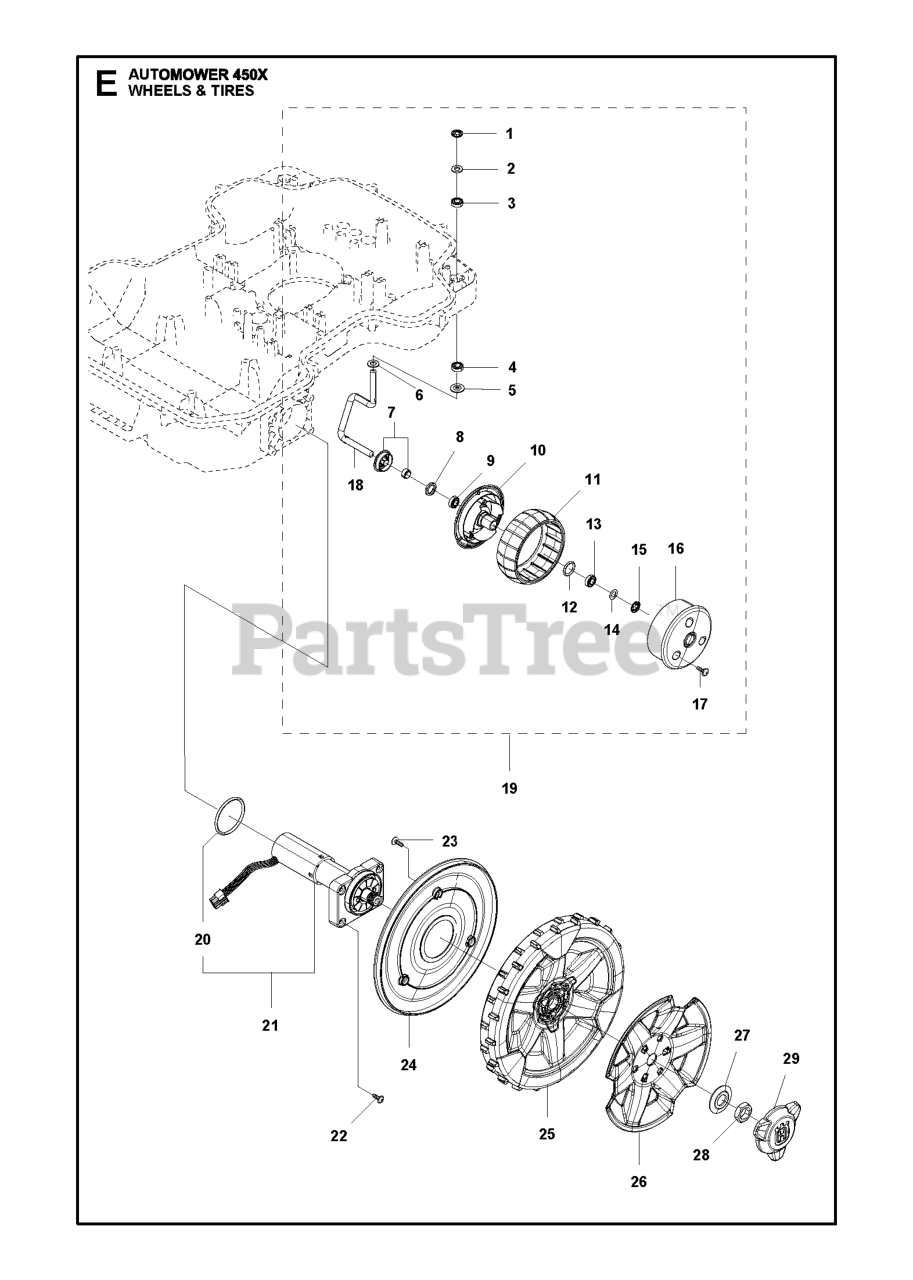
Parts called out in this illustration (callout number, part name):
1	LOCKWASHER PUSH-ON TYPE P 8 BV
2	WASHER DIN 988 13X8X0.5
3	BALL BEARING SINGLE ROW S688
4	BALL BEARING SINGLE ROW S688
5	WASHER FRONT WHEEL CENTER HOLE
6	WASHER DIN 988 13X8X0.5
7	SHIELD KIT
8	SEALING 12X18X3
9	BALL BEARING SINGLE ROW S688
10	WHEEL FRONT WHEEL INSIDE
11	WHEEL RUBBER TYRE
12	O-RING 2,62X15,54
13	BALL BEARING SINGLE ROW S688
14	WASHER DIN 988 13X8X0.5
15	LOCKWASHER PUSH-ON TYPE P 8 BV
16	WHEEL FRONT WHEEL OUTSIDE
17	SCREW 14MM
18	SPINDLE SPINDLE FRONT WHEEL RI
19	WHEEL KIT FRONT
20	O-RING LIGHT GREY
21	MOTOR KIT DRIVE WHEEL
22	SCREW ITXPANT
23	SCREW 14MM
24	COVER REAR WHEEL
25	REAR WHEEL FINE THREAD HUSQVAR
26	WHEEL COVER REAR WHEEL
27	WASHER WASHER REAR WHEEL 16X40
28	HEXAGON THIN NUT
29	HUB CAP REAR WHEEL NO CENTER P
